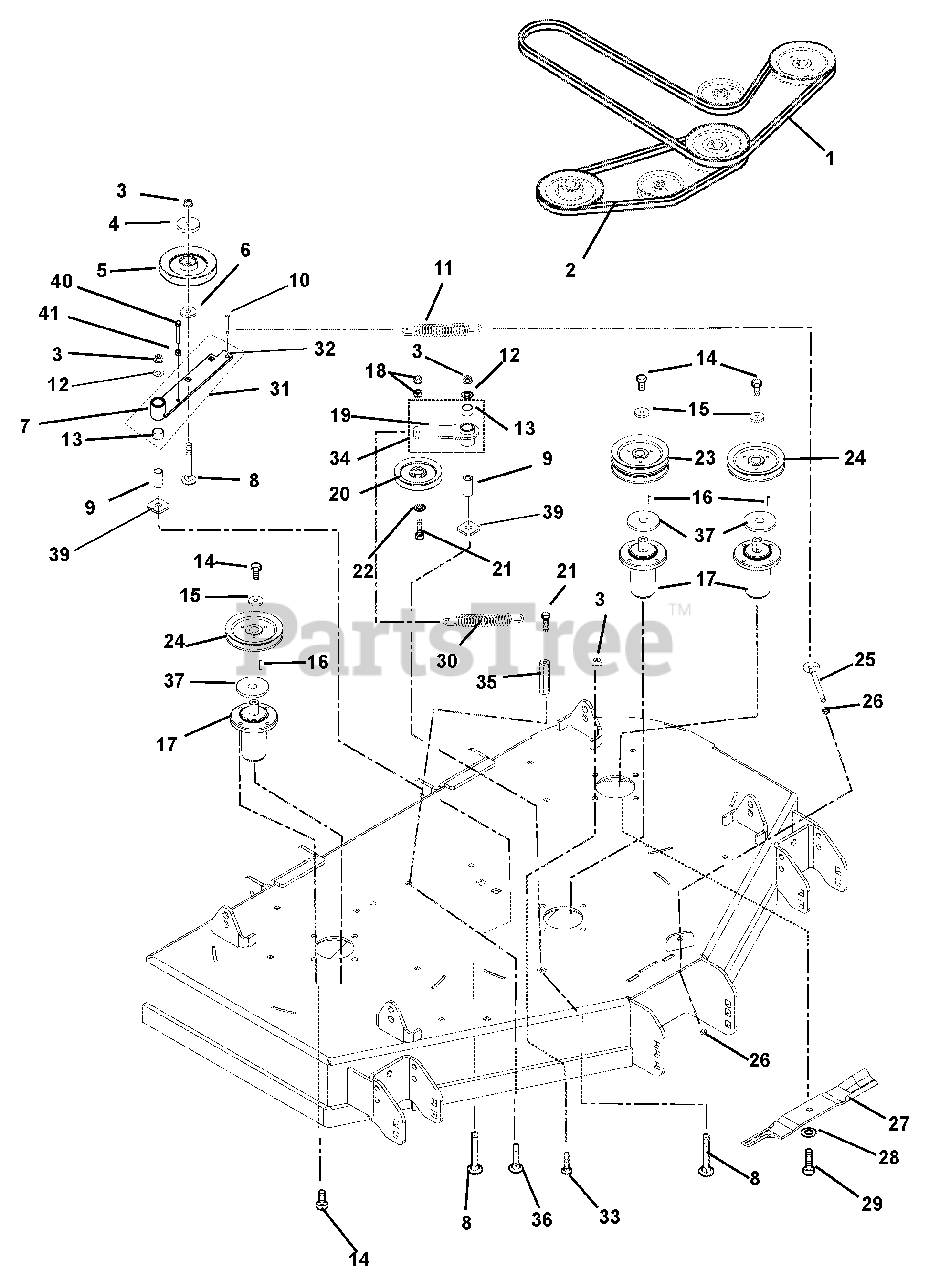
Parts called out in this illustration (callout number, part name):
1	HEX BELT, BB-WRAPPED
2	V-BELT, B-COGGED
3	@NUT-LK-NYL-FLG .50-13 YWZC
4	CAP, IDLER BEARING SEALING
5	PLY-V 6.0 X .500 ID SNGL BRG.
6	BSHG, SPCR .502X.997X.50 PM
7	WMT, IDLER ARM
8	@BLT-RHDSSQNK .50-13X3.50 G5YZ
9	BEARING, PEDESTAL
10	BLT-SHLDR .38-16X.38 SKH
11	SPRING, EXTENSION
12	WSHR-FL-STL .531X1.250X.10 YWZ
13	BSHG, 1.00 X 1.125 X 1.937
14	BLT-HEX .38-16X1.0 GR8 YZ EP30
15	WSHR,FLT STL.406X1.50X.245YWZC
16	KEY, SQ .25X.25X1.00 RC 40-50
17	ASSEMBLY, SPINDLE
18	@NUT-LK-CTR .38-16 YWZC
19	WMT, IDLER PIVOT ARM
20	SHV, .38"ID X 5.00"OD V-IDLER
21	@BLT-HEX .38-16X2.25 GR5 YWZC
22	@WSHR-FL-STL.406X.812X.065 YWZ
23	SHV,DOUBLE 1.0"ID X 5.50" OD
24	SHV,SINGLE 1.0"ID X 5.50" OD
25	BOLT, .38-16X4.50 .62 DIA EYE
26	NUT-HEX-JAM .375-16 YWZC
27	BLADE, 32" (16.25)
28	WSHR-BLVL .669X1.535X.138
29	BLT-HEX .62-18X1.75 GR8 YWZC
30	SPRING, EXTENSION
31	ASM, IDLER PIVOT ARM (PTO)
32	@WSHR-LK .38X.094 REG YWZC
33	BLT-RDHDSHSQNKFT.50-13X1.50 G5
34	ASM, IDLER ARM (DECK)
35	NUT COUPLING .375-16X1.75
36	@BLT-RDHDSHSQNK.38-16X1.0 G5YZ
37	SLINGER, DUST
38	@BLT-RDHDSQNK .50-13X3.00 G5YZ
39	WSHR-FLT .640X1.75X.250
40	@BLT-HEX .38-16X2.75 GR5 YWZC
41	@NUT-HEX .38-16 YWZC
